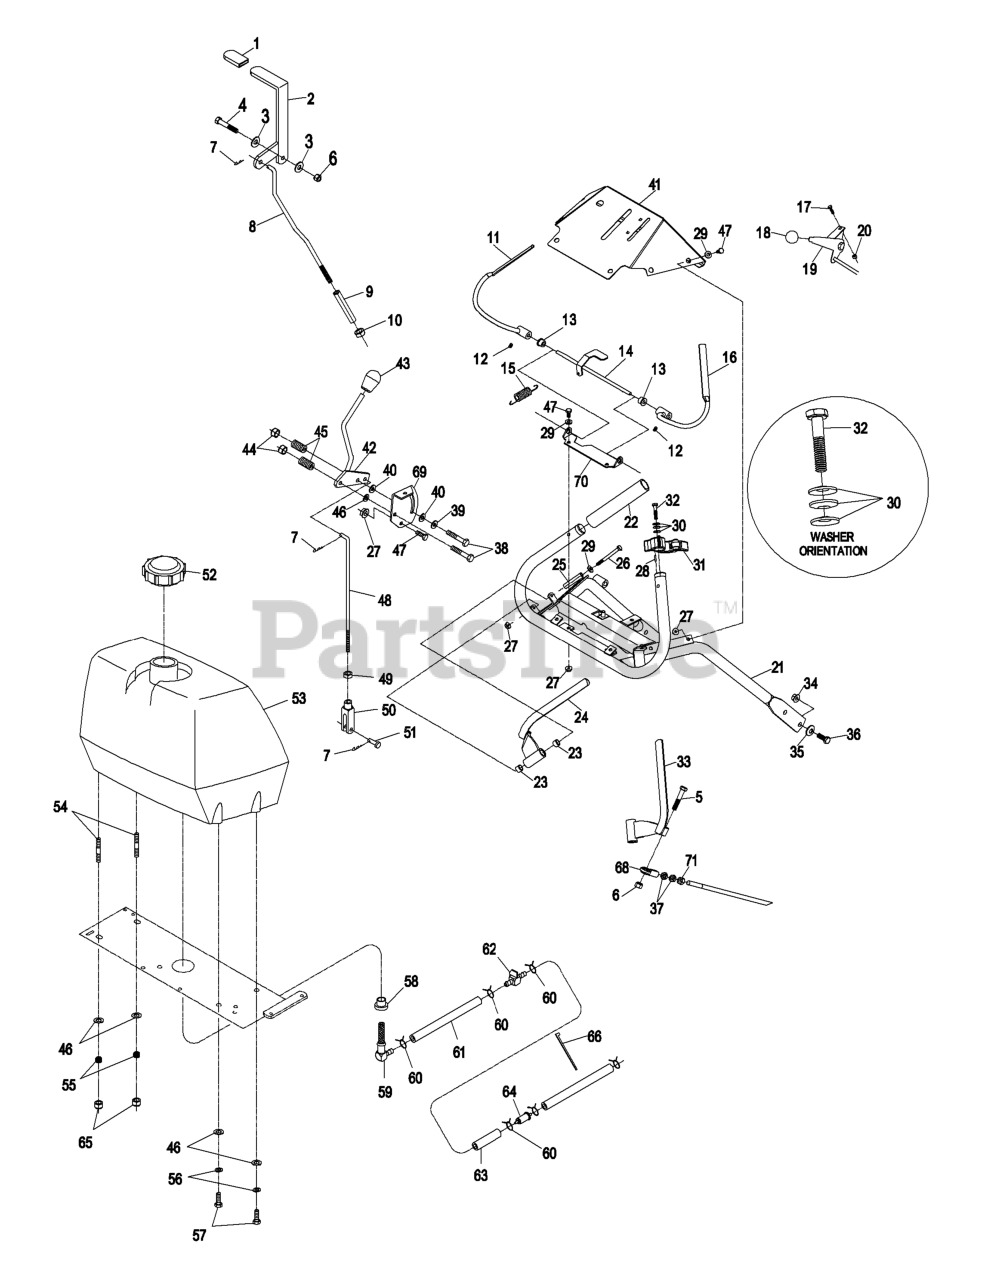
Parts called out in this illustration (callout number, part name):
1	GRIP-LEVER
3	WASHER-FLAT
4	SCREW-HH
5	SCREW-HH
6	NUT-LOCK, NI
7	PIN-COTTER
8	LINK,BLADE ENGAGE (PLTD)
9	TURNBUCKLE
10	NUT-HEX
12	SCREW-SET
13	BUSHING-NYLON
14	WLD,OPC LEVER AXLE
15	SPRING-EXTENSION
17	BOLT-CARR
18	KNOB-BALL
19	CONTROL,THROTTLE
20	NUT-LOCK, NI
21	WLD,UPPER ECS HANDLE
22	GRIP-BAR, HANDLE
23	BUSHING-SLEEVE
25	BUSHING-LEVER, DRIVE
26	SCREW-HH
29	WASHER-FLAT
30	WASHER-SPRING
31	ASM,LATCH RH THUMB
32	SCREW-HH
34	NUT-HHF, WHIZ
35	WASHER-BELLEVILLE
36	SCREW-HH
37	NUT-HJ
38	SCREW-HH
39	WASHER-FRICTION
40	WASHER-FRICTION
43	KNOB, FE.LCKG. BLACK
44	NUT-LOCK, NI
45	SPRING-COMPRESSION
46	WASHER-PLAIN
47	SCREW-HH
48	ROD,SPEED CONTROL
49	NUT-JAM
50	YOKE-ADJUSTABLE
51	PIN-CLEVIS
52	CAP-FUEL
54	STUD
55	SPRING-TANK, FUEL
56	WASHER-LOCK
57	SCREW-HH
59	ELBOW-TANK, FUEL
61	HOSE-FUEL
62	VALVE-FUEL
63	HOSE-FUEL
64	Kawasaki Pn 41019-1055
65	NUT-LOCK, NI
66	TIE-PLASTIC
67	RH DRIVE LEVER ASM
68	JOINT-BALL, END
69	BRACKET,SHIFTER SLIDE (PL
70	BRACKET,OPC AXLE
71	NUT-HEX
